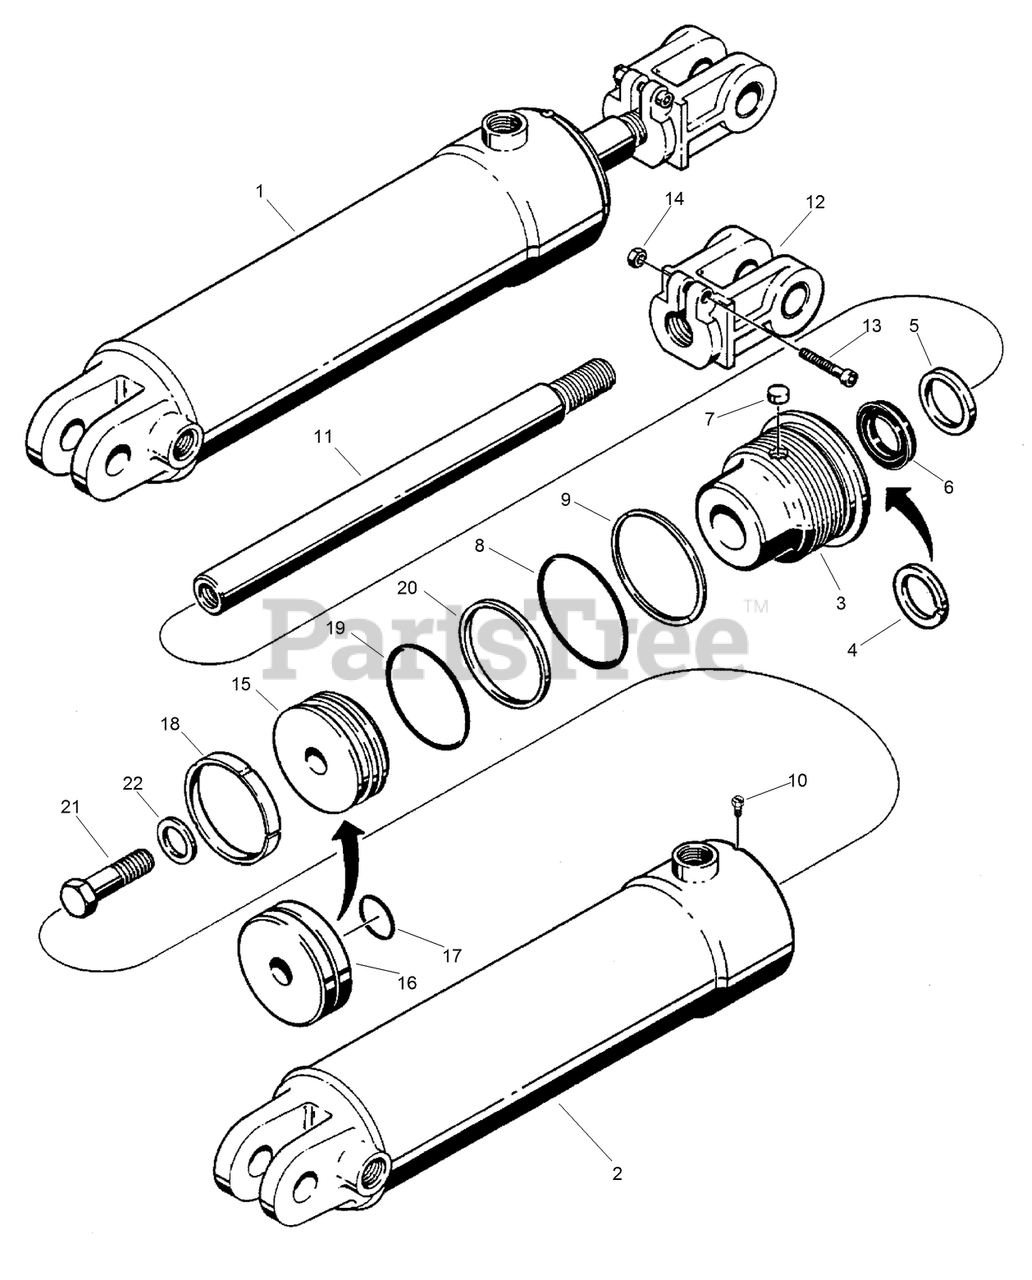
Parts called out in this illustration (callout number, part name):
1	ASSEMBLY - Cylinder
2	TUBE - Cylinder
3	GLAND - Cylinder
4	SEAL - Buffer (If used)
5	SEAL - Wiper, Piston Rod
6	RING - Piston Rod
7	PLUG - Nylon (If used)
8	O-RING-3 ID x 1/8 inch wide, gland
9	RING-backup, gland O-ring
10	SCREW-SELF TAPPING
12	CLEVIS - Adjustable, Piston Rod (Includes items 13 & 14)
13	BOLT - 3/8 x 1-3/4
14	NUT - 3/8
15	PISTON - Double Groove (If used)
16	PISTON - Single Groove (If used)
17	O-RING - 1-1/4 x 1/16 (Used with item 16)
18	RING-WEAR
19	O-RING - 2-1/2 ID x 1/8
20	RING - Piston Rod
21	BOLT - 3/4 NF x 2; 8
22	WASHER
